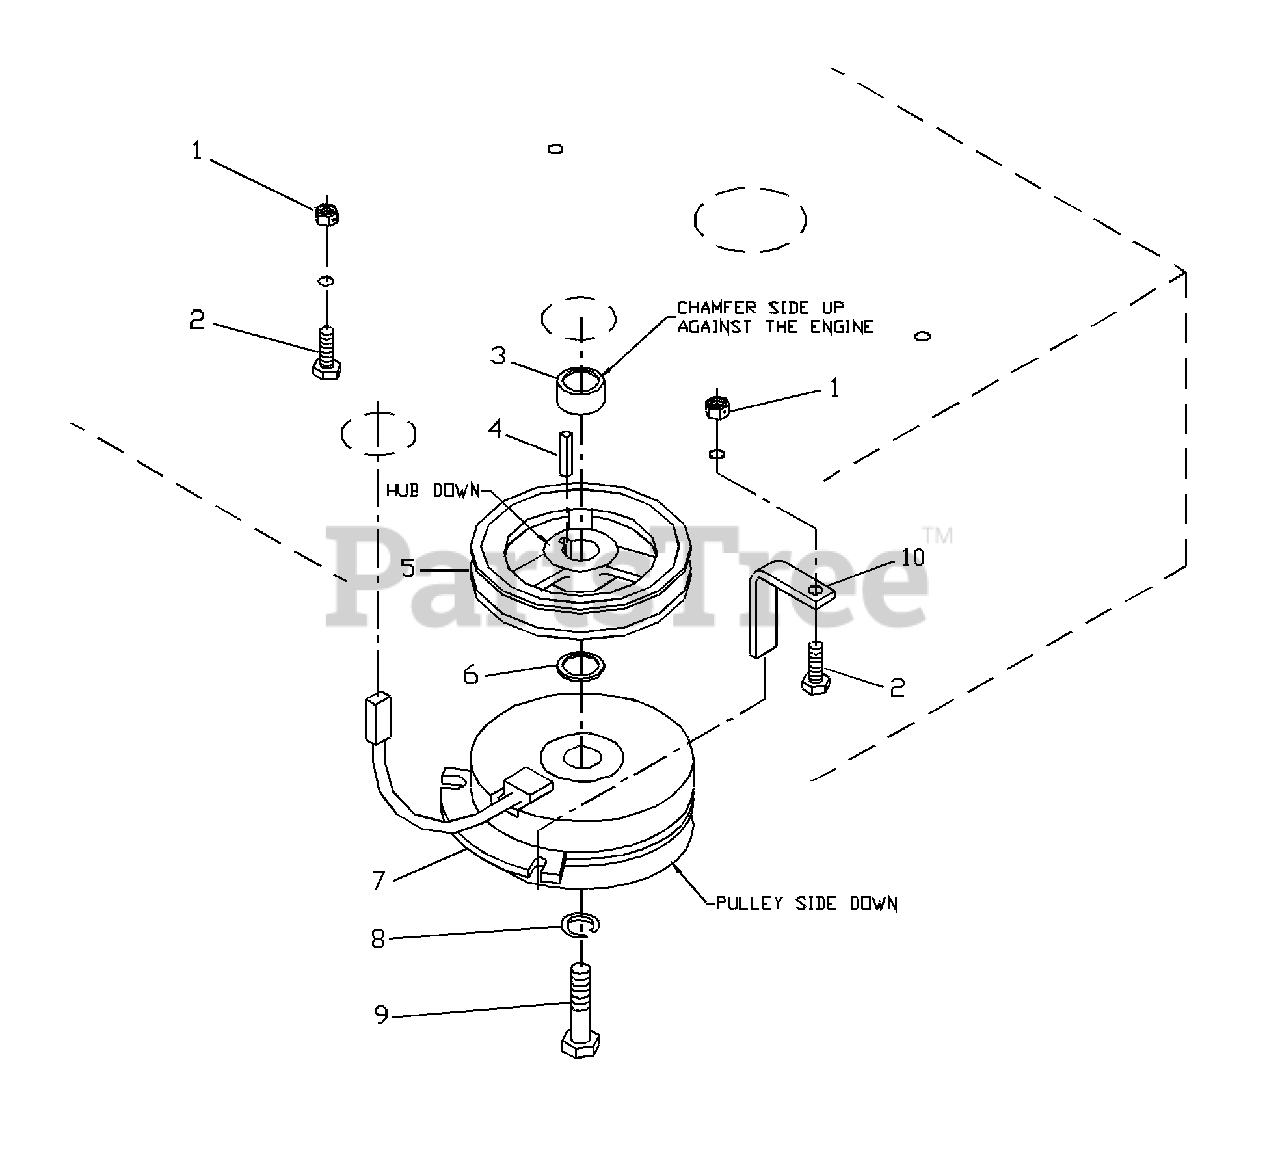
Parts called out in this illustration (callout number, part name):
1	NUT 5/16C CENTERLOCK
2	HCS 5/16C X 1 3/4
4	KEY 1/4 SQ. X 1 1/8
6	10GA. MACHINERY BUSHING
7	ELECTRIC CLUTCH
8	7/16 LOCKWASHER
9	HCS 7/16F X 2 1/2
10	CLUTCH TIE DOWN
